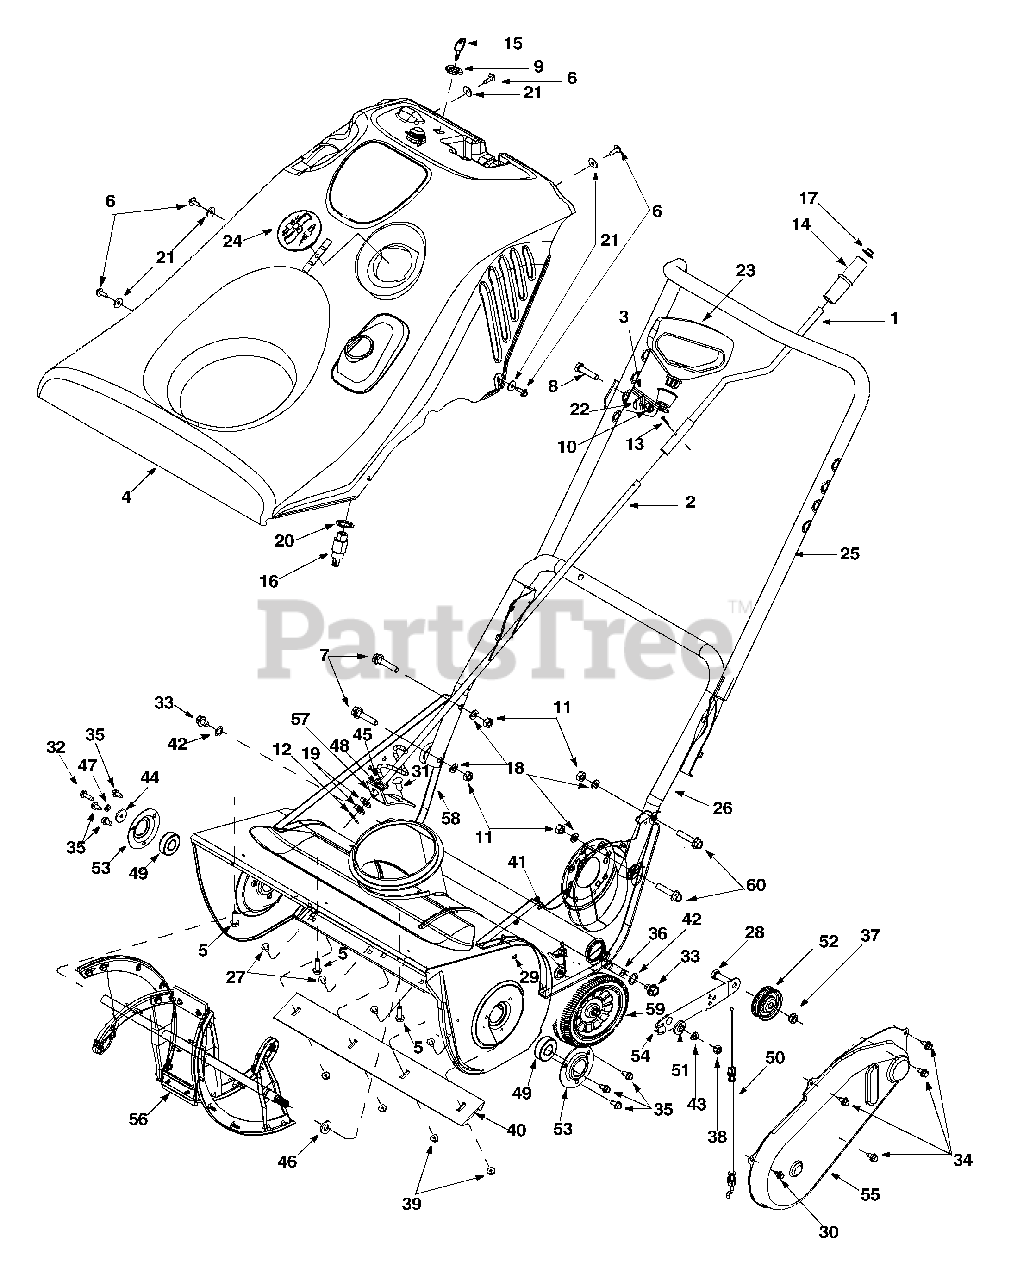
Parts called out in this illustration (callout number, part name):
3	Bracket Assembly: Mitten Grip
4	Shroud: Yellow, 7 Hp. Electric
5	TT Screw 1/4-15 x 0.75"
6	B Screw #10-16 x 0.625"
7	Hex Fl. Screw 5/16-18 x 1.5"
8	Hex Bolt 5/16-18 x 1.375"
9	Jam Nut
10	Lock Nut
11	Hex Nut 5/16-18
12	Cotter Pin
13	Cotter Pin
14	Knob: Chute Crank
15	Ignition Key
16	Switch: Electric Start Key
17	Push Cap
18	Lock Washer
19	Flat Washer
20	Internal Lock Washer
21	Flat Washer
22	Saddle Washer
23	Mitten Grip Handle
24	Spark Plug Access
28	Hex Bolt
29	Machine Screw
30	B Screw 1/4-14 x 0.375"
31	Carriage Bolt
32	TT Screw 1/4-20 x 0.75"
33	TT Screw 3/8-16 x 0.5"
34	AB Screw 1/4-14 x 0.625"
35	B Screw 1/4-14 x 0.5"
36	Axle Tube
37	Jam Lock Nut
38	Hex Nut 5/16-18
39	Lock Nut
40	Shave Plate
41	Extension Spring
42	Flat Washer
43	Lock Washer
44	Flat Washer
45	Beleville Washer
46	Flat Washer
47	Lock Washer
48	Plastic Bushing
49	Ball Bearing
50	Clutch Cable
51	Shoulder Spacer
52	Flat Idler
60	Hex Fl. Screw 5/16-18 x 1.25"
